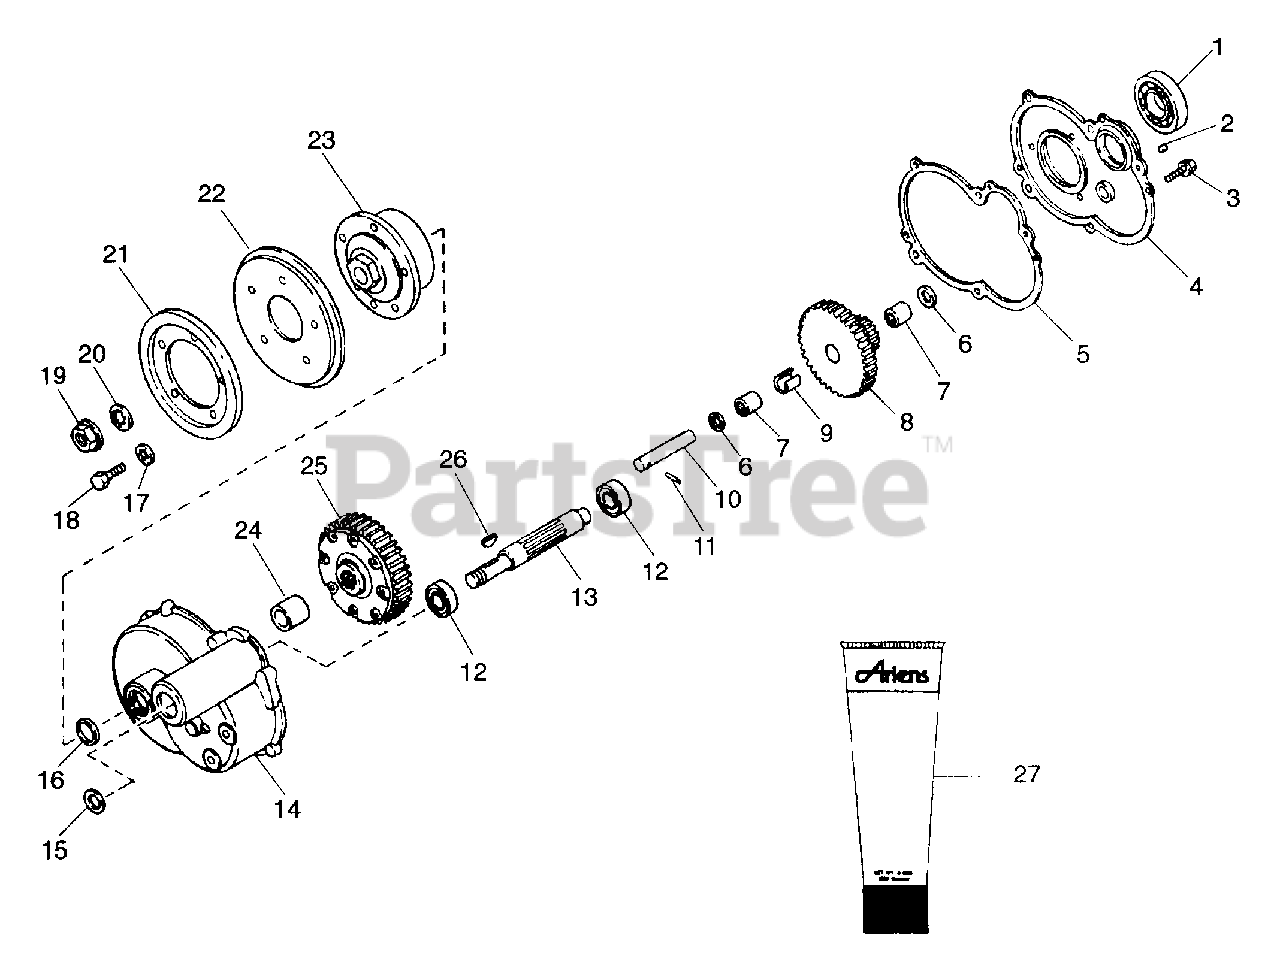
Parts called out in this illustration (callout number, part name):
1	BRG-BALL 1.125X2.50X.63
2	BREATHER
3	SCR-TAP 10-24X1.0 HWH PL TR
4	GEAR CASE COVER ASSEMBLY
6	WSHR-FL-STL .505X.875X.024 PL
7	BRG-NEEDLE .50X.688X.625
8	PINION & GEAR W/BEARING ASSEMB
9	SPACER - CUT .640X.688X.625
10	IDLER SHAFT
11	PIN-ROLL .125X.75
12	BRG-BALL .625X1.375X.44
13	PINION SHAFT
14	SERVICE GEAR CASE
15	WSHR-FL-STL .627X.990X.032
16	SEAL .875X1.125X.125
17	WSHR-LK-INT .313X.030 PL
18	BLT-HEX .31-18X.50 PL GR2
19	NUT-LK-NYL.625-18 PL
20	WSHR-LK-INT .625X.045 PL
22	FRICTION DISC
23	FRICTION DISC HUB
24	BSHG-SLV .875X1.125X1.046
25	DIFFERENTIAL ASSEMBLY
26	KEY-WDRF .188X.875X.375 SAE11
27	MULTIPURPOSE GREASE
